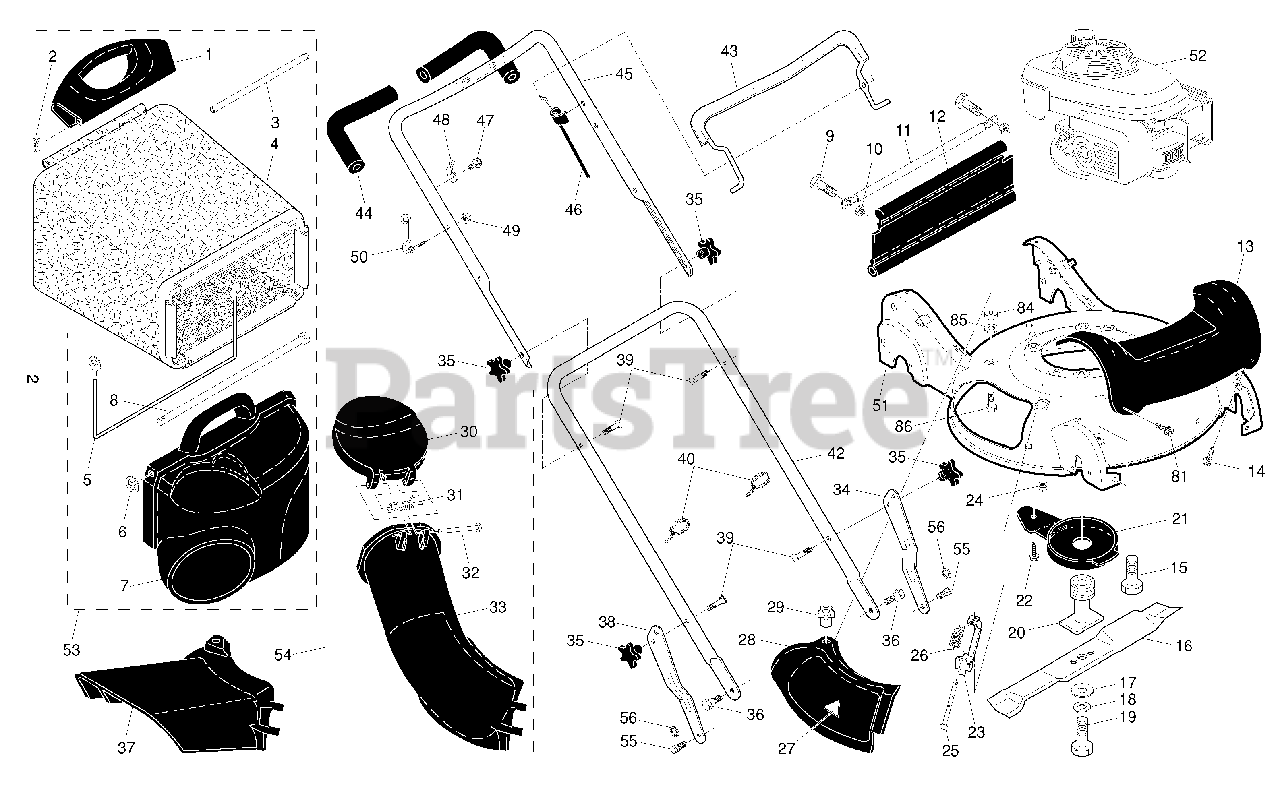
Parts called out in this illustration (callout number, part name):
1	Handle, Grassbag, Rear
2	Hairpin Cotter
3	Rod, Rear Handle, Grassbag
5	Frame, Grassbag
7	Door, Grassbag
8	Rod, Pivot
10	Nut, Hex, Nylock 1/4-20
11	Tube, Rear Skirt
12	Rear Skirt
13	Cover, Front
14	Screw, Hex Washer Head
15	Bolt, Engine Mounting
16	Blade, 21"
17	Washer, Hardened
18	Washer, Lock
19	Bolt, Hex Head, Grade 8 3/8-24
20	Adapter, Blade
21	Debris Shield
22	Screw, Hex Head, Serrated
23	Mounting Bracket, Mulcher Door
25	Rod, Hinge
26	Spring, Mulcher Door
27	Decal, Danger
28	Mulcher Door
30	Door, Discharge Chute
31	Spring, Door, Discharge Chute
32	Rod, Door, Discharge Chute
33	Discharge Chute, Plastic
34	Adjustment Bracket, Lower Handle, LH
35	Knob, Star
36	Bolt, Shoulder
37	Deflector, Discharge
38	Adjustment Bracket, Lower Handle, RH
39	Bolt, Handle
40	Wire Tie
42	Handle Assembly, Lower
43	Bail, Control
44	Grip, Foam
45	Handle Assembly, Upper
46	Cable, Engine Zone Control
48	Bracket, Upstop
49	Nut, Hex
50	Rope Guide
51	Kit, Lawn Mower Housing Assembly
52	Engine, Honda, Model Number GCV160-LAS3A (Order parts from Engine Manufacturer)
53	Grassbag Assembly, Complete
54	Discharge Chute Assembly, Complete
55	Stud, Shoulder, T45
56	E-Ring, T45
81	Screw 13-16 x 5/8
84	Nut, Hex
85	Washer
86	Bolt, Hex Head
